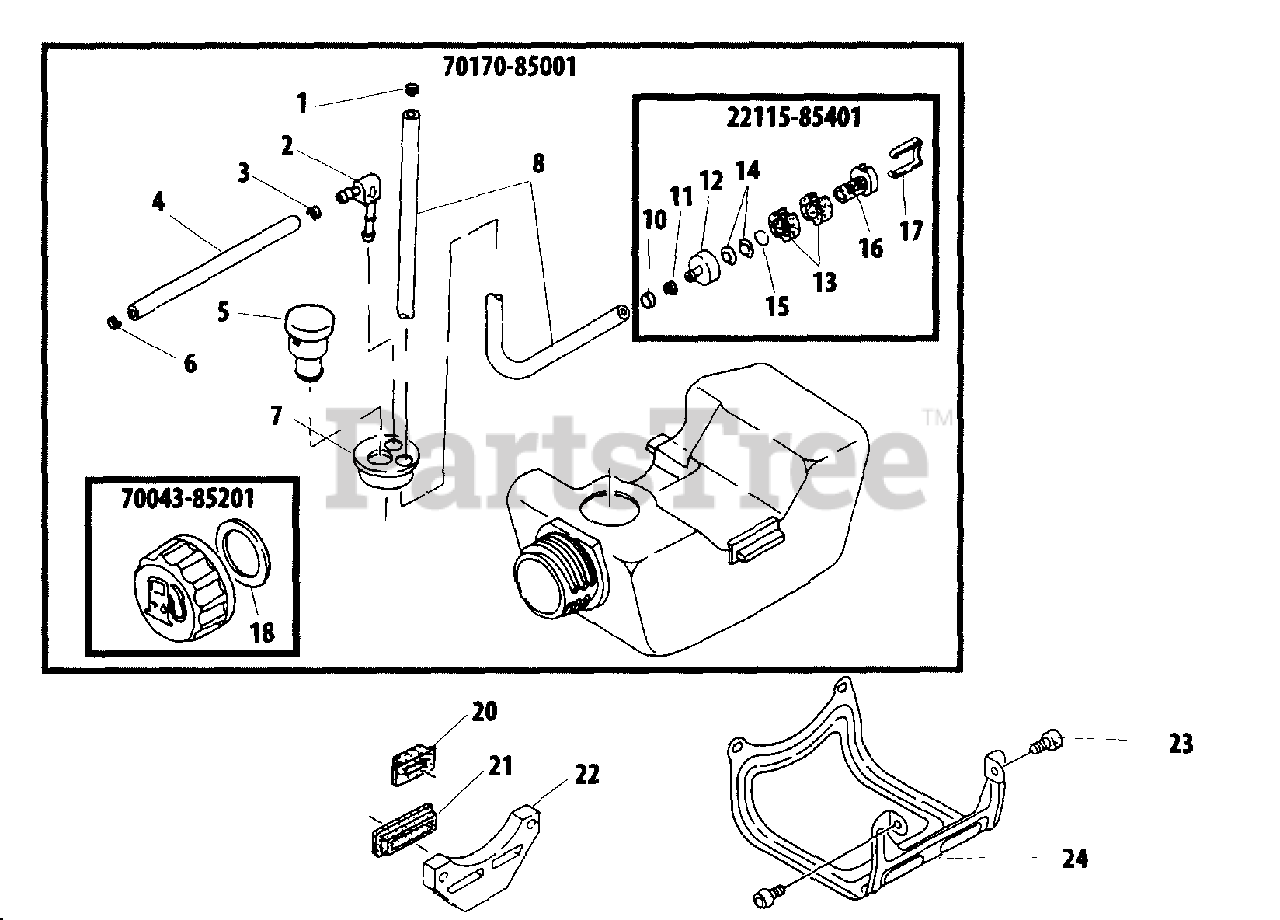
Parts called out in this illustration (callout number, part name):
1	RING, RETAINING
2	CONNECTOR, PIPE
3	RING, RETAINING
4	PIPE - RETURN
5	VENT, FUEL TANK
6	RING, RETAINING
7	GROMMET
8	PIPE - FUEL
10	VENT, FUEL TANK
11	RING, RETAINING
12	WEIGHT, FUEL FILTER
13	FILTER, FUEL
14	STRAINER
15	RING, RETAINING
16	CASE, FILTER
17	CLIP, FILTER
18	GASKET, CAP
20	CUSHION, TANK
21	CUSHION, TANK
22	BRACKET, FUEL TANK
23	SCREW - 5X12
24	GUARD, FUEL TANK
22115-85401	FILTER, FUEL
70043-85201	CAP ASSY
70170-85001	FUEL TANK ASSY
